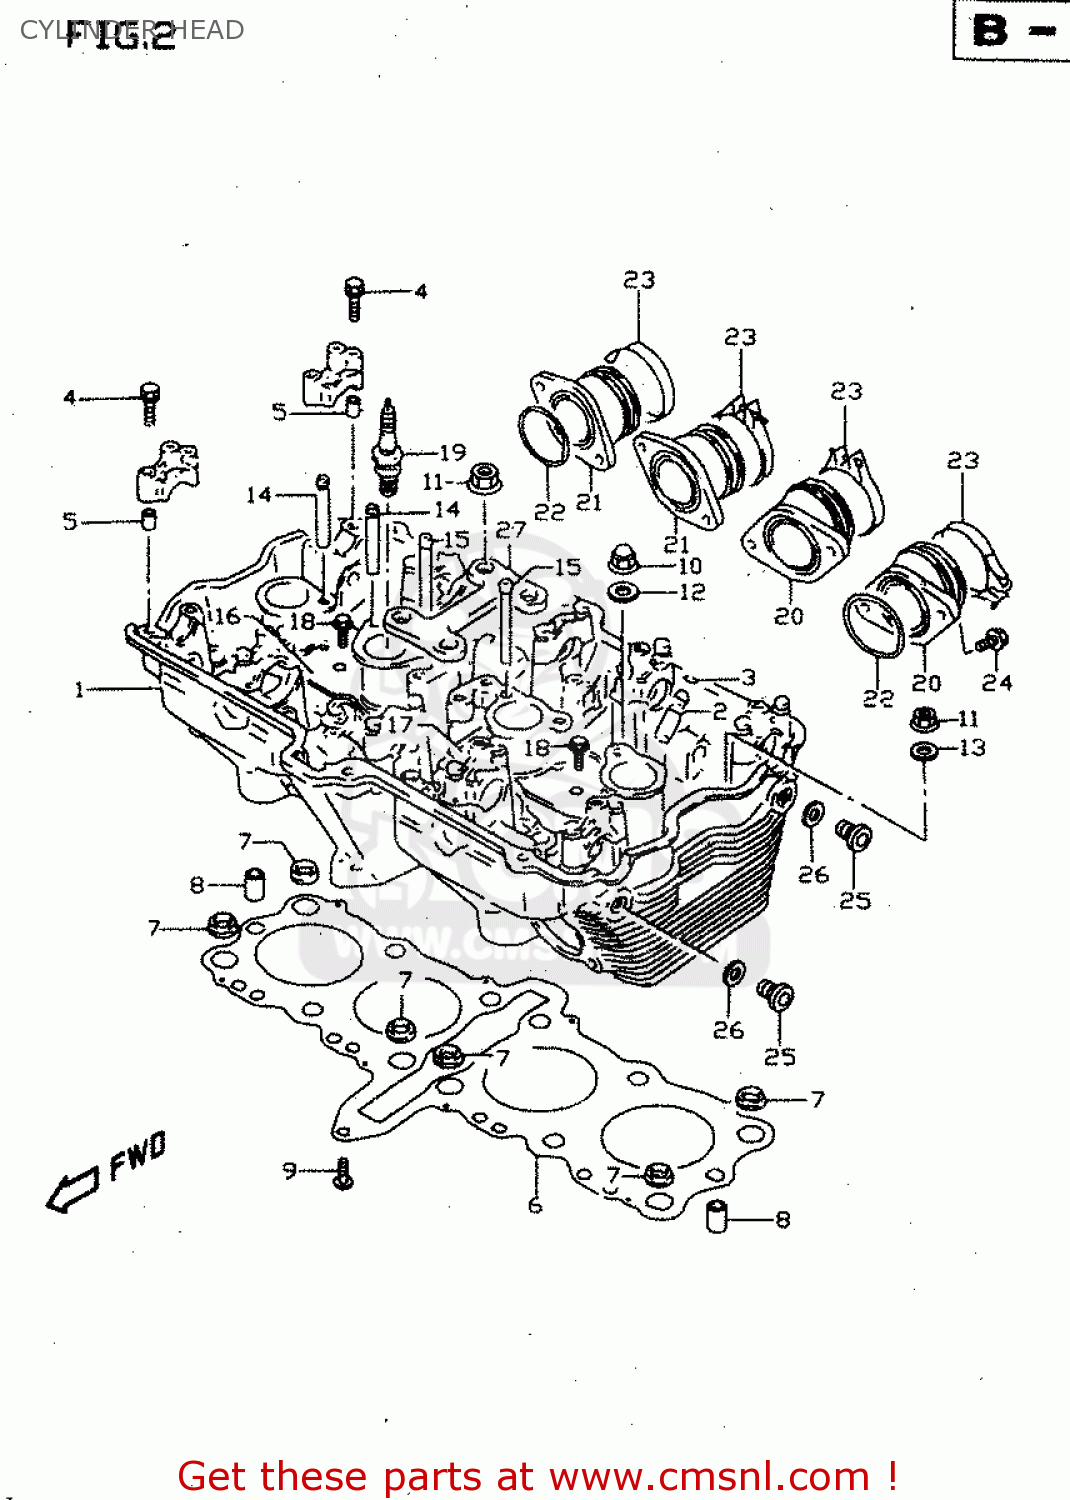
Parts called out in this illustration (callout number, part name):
1	HEAD,CYLINDER
2	GUIDE,VALVE
3	RING,SNAP
4	BOLT(6X39)
5	PIN(6.2X8X11)
6	GASKET,CYLINDER HEAD (NAS)
7	O RING,HEAD GASKET
8	PIN
9	BOLT
10	NUT
11	NUT
12	GASKET(10.2X20X2).3 (NAS)
13	WASHER (10.5X22X2.3)
14	PIPE,OIL NO.1
15	PIPE,OIL NO.3
16	PLATE,OIL PIPE,R
17	PLATE,OIL PIPE,L
18	BOLT
19	PLUG,SPARK(CR9EK)
20	PIPE ASSY,INTAKE,L
21	PIPE ASSY,INTAKE,R
22	O RING(D:2.4,ID:39.7)
23	CLAMP
24	BOLT MAGNETO S
25	PLUG
26	GASKET(13.8X18.8X4.8) (NAS)
27	PLATE,HEAD REINF
